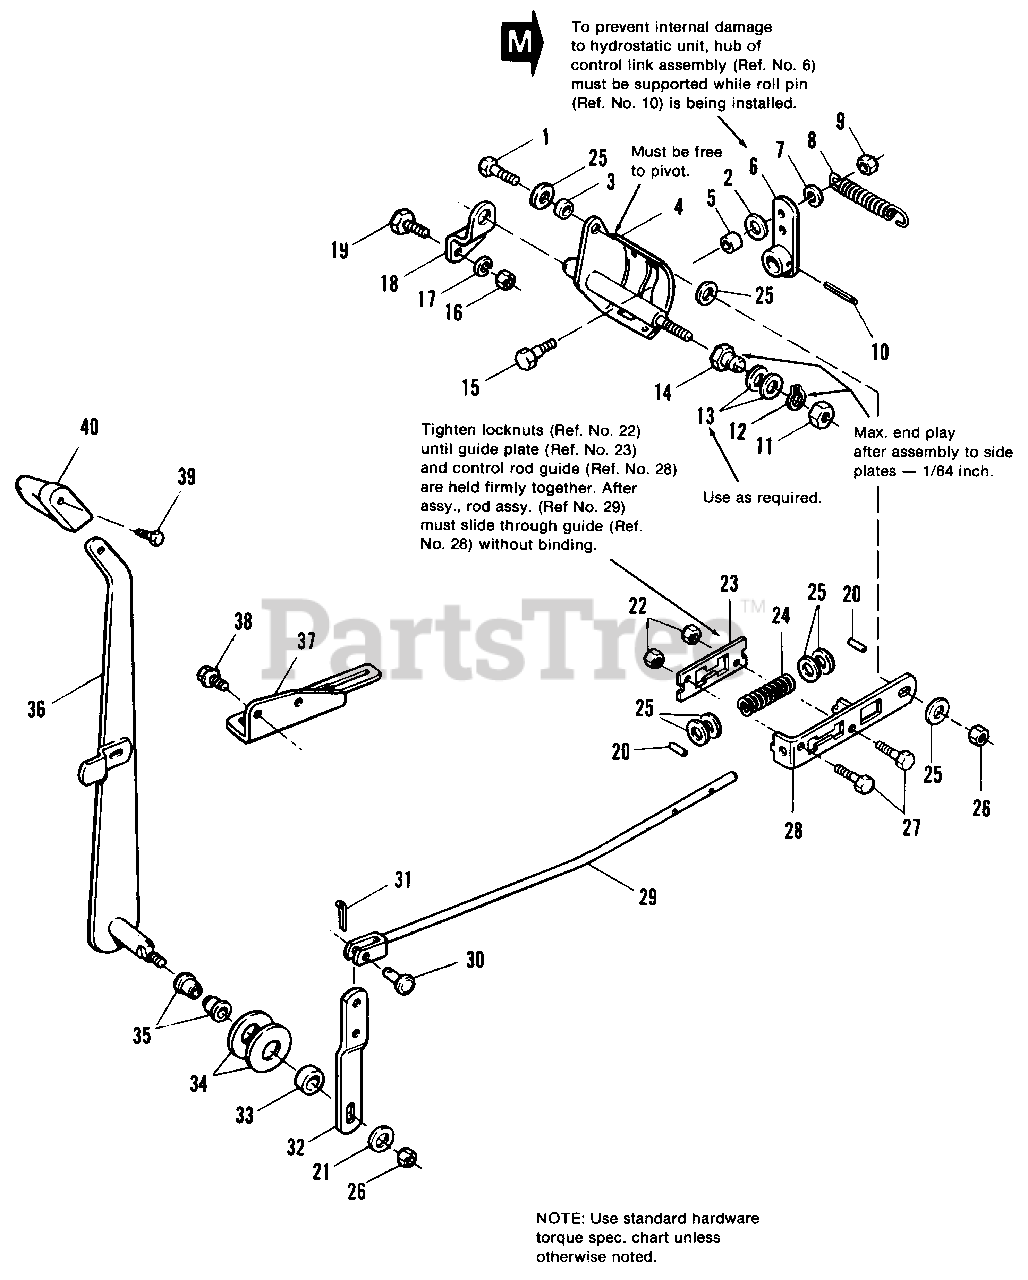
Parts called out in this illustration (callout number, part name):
1	CAPSCREW, Hex Hd., 3/8-16 x 1-1/4
2	WASHER, Plain, 1/4
4	SHAFT ASSY.
5	ROLLER, Cam
6	LINK ASSY., Control
7	LOCKWASHER, 1/4
9	NUT, Hex, Full, 1/4-20
10	PIN, Roll, 1/4 x 1-1/4
11	LOCKNUT, Hex, Jam, 1/2-13
12	RING, Retaining
13	SHIM (as required)
14	NUT, Adjusting
15	BOLT, Shoulder
16	NUT, Hex, Full, 5/16-18
17	LOCKWASHER, 5/16
18	BRACKET, Pivot
19	SCREW, Special
20	PIN, Roll, 1/8 x 5/8
21	WASHER, Plain, 3/8
22	LOCKNUT, Hex, 1/4-20
23	PLATE, Guide
25	WASHER, 3/8
26	NUT, Hex, Esna, 3/8-16
27	CAPSCREW, Hex Hd., 1/4-20 x 1-1/4
28	GUIDE, Control Rod
29	ROD ASSY., Control
31	PIN, Cotter, 3/32 x 3/4
34	WASHER, Spring
36	LEVER ASSY., Control
37	QUADRANT
38	SCREW, Hex, Flange, Whiz, 5/16-18 x 1/2
39	SCREW, Plastite, 1/4-20 x 1-1/4
40	KNOB, Soft
